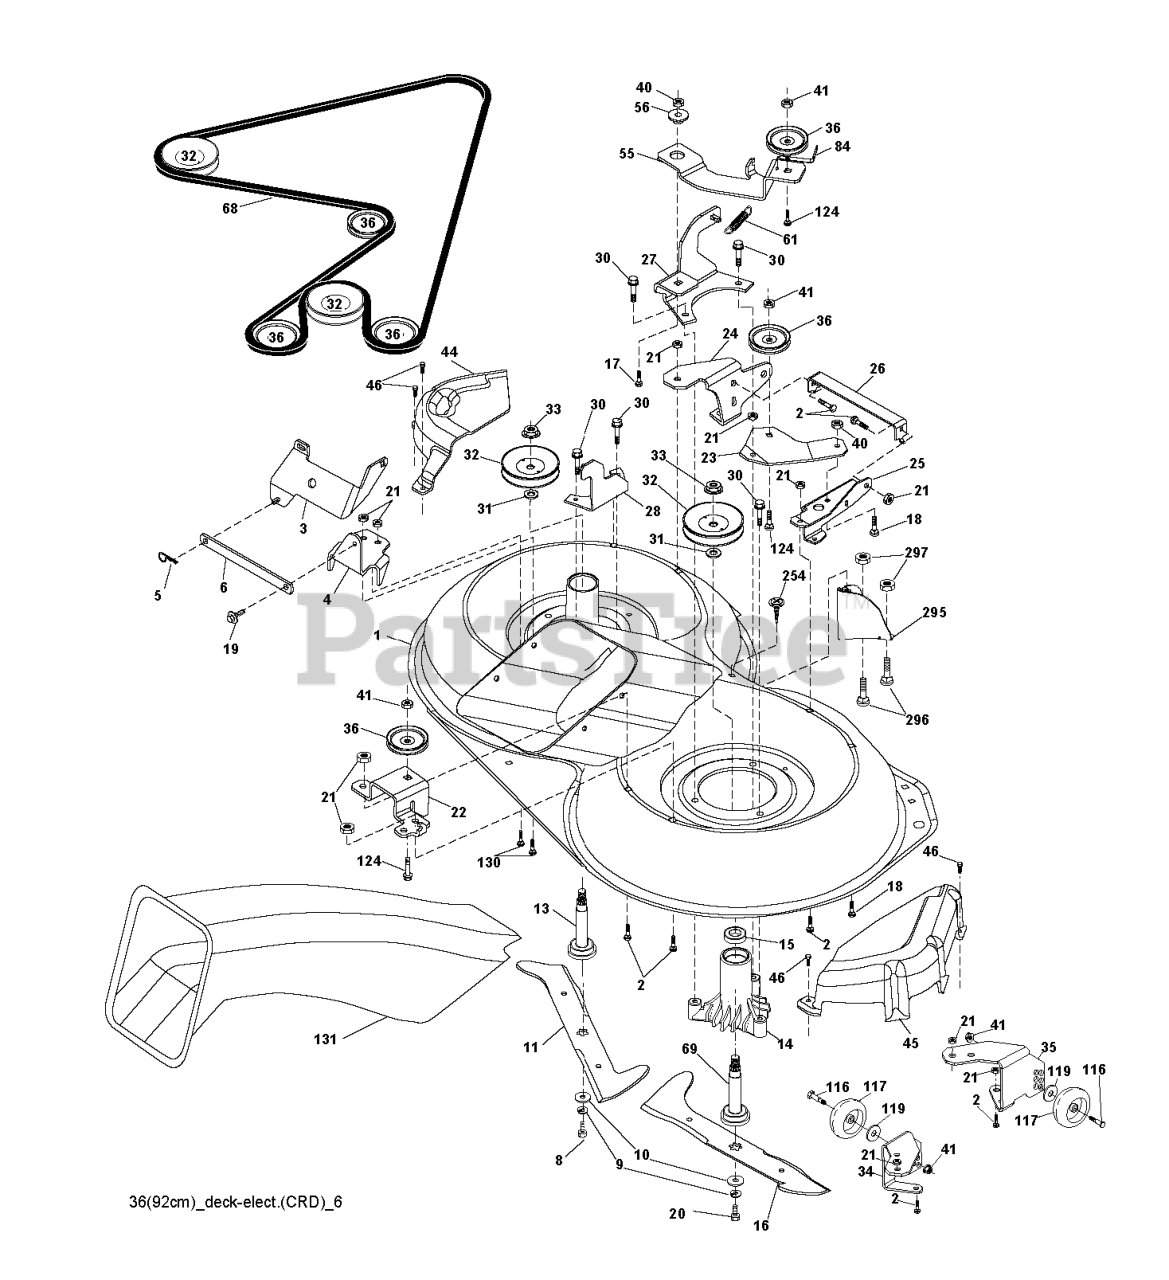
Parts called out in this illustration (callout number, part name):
2	RP BOLT 5/16-18 X3/4 ZN/YEL GR
5	RETAINER-SPRNG RB
6	BAR.SWAY.92.CRD
8	BOLT.3/8-24X1.25 GR8
9	LOCKWASHER
10	WASHER.BLADE
13	SHAFT ASM VENT
14	HOUSING.MANDREL.VENTED (MACHD)
17	BOLT.3/8-14X1.25
19	BOLT SHD 5/16-18
20	BOLT.3/8-24X1.25GR8. LHTHRD
21	LOCKNUT
26	SUPPORT
30	SCREW, WASHER HEAD
31	WASHER.SPACER.MANDREL
32	PULLEY MANDREL
33	NUT.FLANGE.LOCK.TOP
36	PULLEY.IDLER.4.25
41	NUT LOCK FLG 3/8-16 UNC
45	COVER.MANDREL.RH.CRD
46	SCREW.1/4-20X5/8
55	ARM.IDLER.92 CRD.2006
56	SPACER.RETAINER.MOWER
61	SPRING
68	BELT.DRIVE.92CM.CRD.2006
69	SHAFT.ASM.W/LWR.BRG.RH.THREAD
84	KEEPER, BELT IDLER
116	BOLT.SHOULDER.3/8-16X3-5/8.
117	RP WHEEL. GUAGE RALLY
119	WASHER
124	BOLT.3/8-16X1.50
130	BOLT.CARR.SQNK.5/16-18UNC.X3/4
131	CHUTE BAGGER
254	SCREW 3/8-16X1
296	BOLT
297	NUT CENTERLOCK
